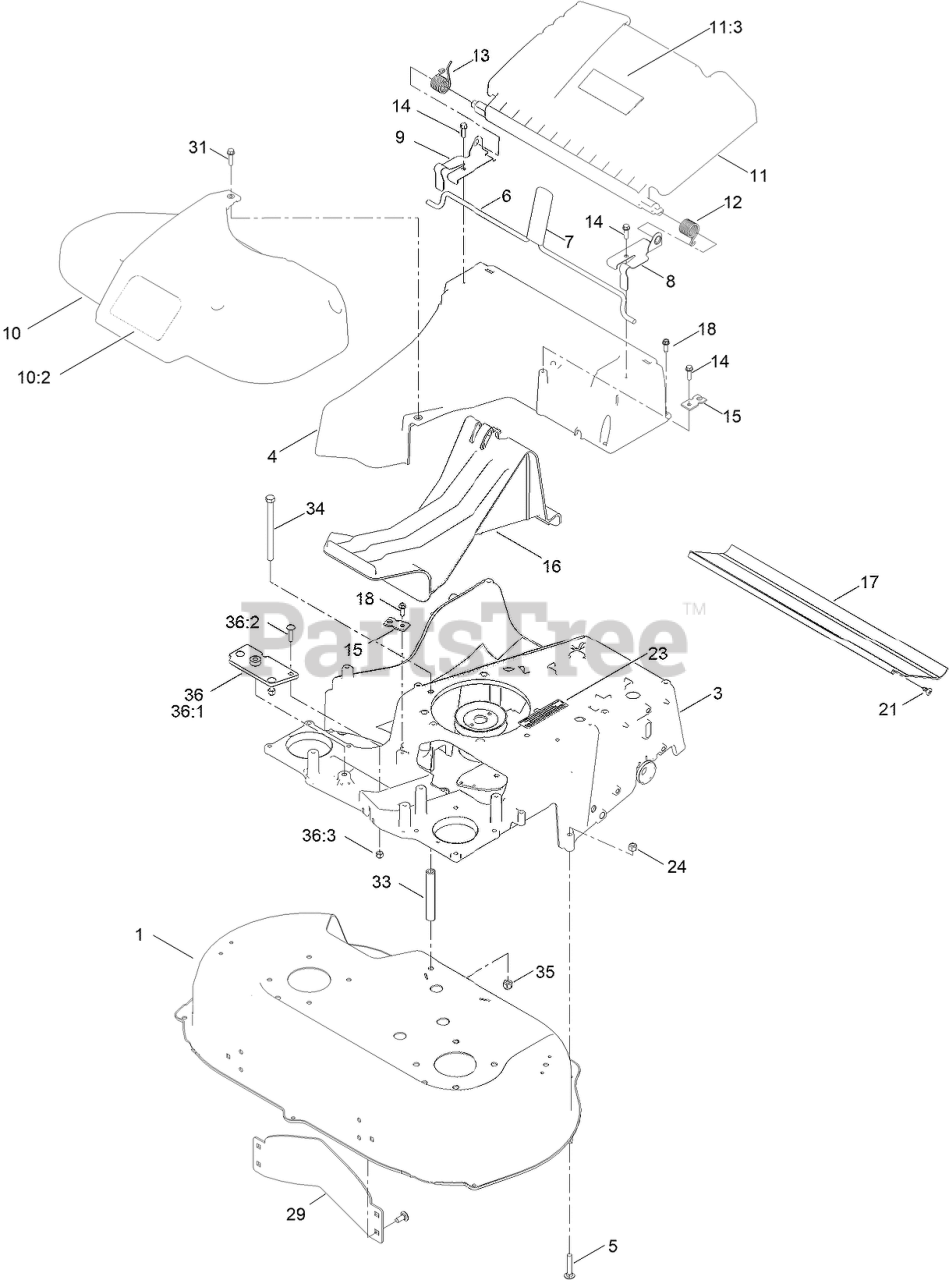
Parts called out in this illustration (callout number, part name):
1	HOUSING ASM
3	FRAME-30"
5	BOLT-CAR
6	ROD-RELEASE, HANDLE
7	GRIP-LEVER
8	BRACKET-DOOR, LH
9	BRACKET-DOOR, RH
10	BELT COVER ASM
10:2	DECAL-COVER, BELT
11	REAR DEFLECTOR ASM
11:3	DECAL-WARNING
12	SPRING-TORSION
13	SPRING-TORSION
14	SCREW-HWH
15	BRACKET-CABLE, TRACTION
16	PLUG-MULCH
17	SHIELD-TRAILING
18	SCREW-HWHTF
21	SCREW-PTH
23	DECAL-ARRESTOR, SPARK
24	NUT-LOCK, NI
29	BAFFLE-CONTROL
31	SCREW-HWHTF
33	SPACER-SHIELD
34	SCREW-HH
35	NUT-HEX
36	FRAME PLATE KIT
36:1	PLATE-FRAME
36:2	SCREW-CARR
36:3	NUT-LOCK, NI
